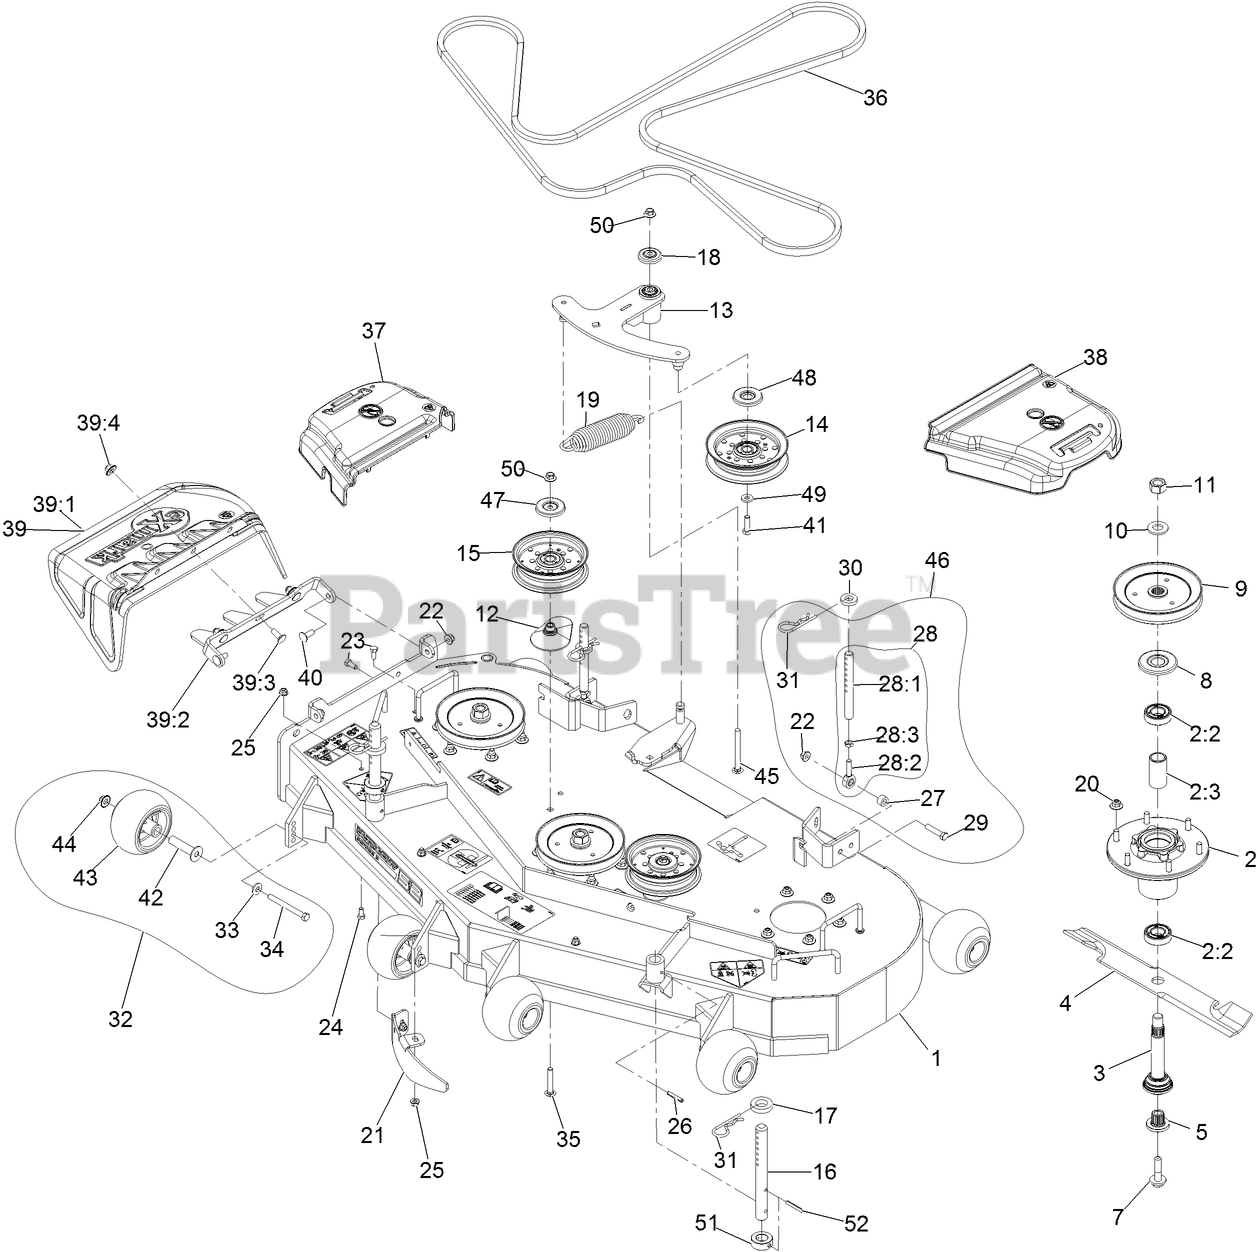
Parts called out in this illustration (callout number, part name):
1	ASM, DECK W/ DECALS, 52
2	ASM-CUTTER HSG WITH BEARINGS
2:2	BEARING-BALL
2:3	SPACER-BEARING
3	ASM-SPINDLE AND SEAL
5	BUSHING,SPLINED
7	SCREW,SEMS 1/2-20 X 2.19
8	GUARD,BEARING TOP .989
9	SHEAVE,BLADE DRIVE 6.50
11	NUT-HEX
12	SPACER-PULLEY
13	ASM, DECK IDLER
14	IDLER-PULLEY, FLAT
15	IDLER-PULLEY, FLAT 5.00X1
16	ROD, DECK SUPPORT TTS
17	SPACER-DECK SUPPORT
18	GUARD-TOP
19	SPRING-EXTENSION
20	Nut-Nyloc 3/8-16 Flg
21	BAFFLE, DOGLEG
22	NUT-HF, NI
23	SCREW-HH
24	SCREW-HH
25	NUT-HF, NI
28:1	LINK,SUPPORT
28:2	BALLJOINT
28:3	NUT-HJ
29	SCREW-HH
31	PIN,HAIR COTTER
32	KIT, ANTI-SCALP ROLLER
33	WASHER-BELLEVILLE
34	SCREW-HH 3/8-16 X 3 3/4 GR 8
35	BOLT-CARR, SHORT NECK
36	BELT, DECK
37	COVER-BELT, RH
38	COVER-BELT, LH
39	ASM, DISCHARGE CHUTE
39:1	CHUTE,DISCHARGE
39:2	BRACKET, DISCHARGE CHUTE
39:3	SCREW-CARR
39:4	Nut-Nyloc 3/8-16 Flg
40	SCREW-CARR
41	SCREW-HH
42	AXLE, ROLLER
43	ROLLER-SCALP, ANTI
44	Nut-Nyloc 3/8-16 Flg
45	SCREW-CARR
46	KIT,SUPPORT LINK W/PIN
47	SHIELD-DUST
48	SHIELD-GUARD, DUST
51	COLLAR, DECK HEIGHT PIN
52	PIN-ROLL
